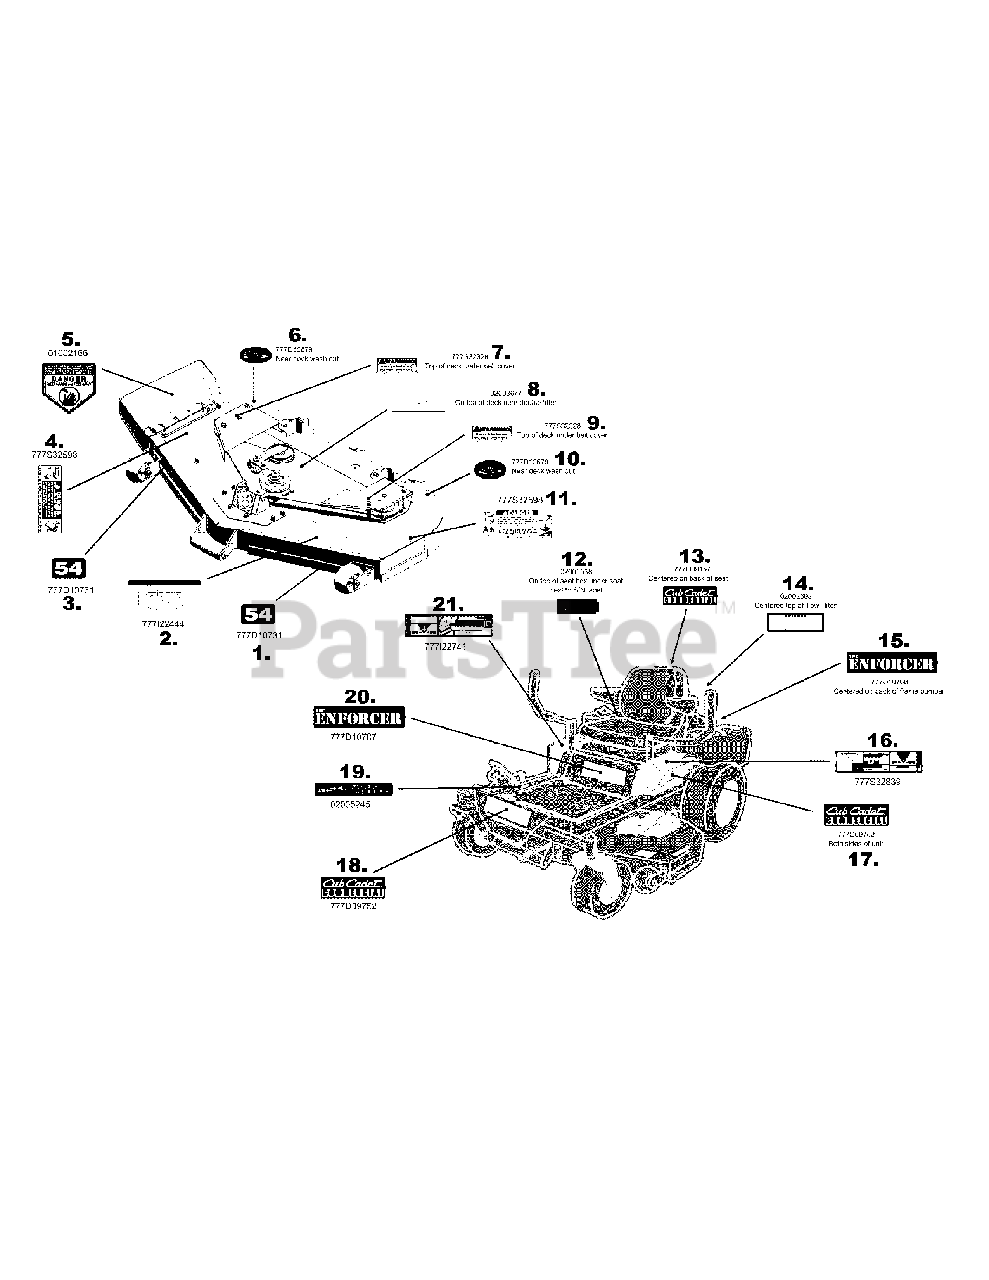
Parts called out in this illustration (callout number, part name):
1	LABEL-54" DECK
2	DECAL-50' DECK BELT RT
3	LABEL-54" DECK
4	LABEL-RZT DECK WARNG STRAIGHT
5	LABEL-HANDS & FEET WALKBEHINDS
6	LABEL-DECK WASH
7	DECAL-WARNING
8	LABEL-DECK BELT ROUTE
9	DECAL-WARNING
10	LABEL-DECK WASH
11	LABEL-RZT DECK WARNG STRAIGHT
12	LABEL-PATENT
14	LABEL-WARNING TOW HITCH
15	LABEL-ENFORCER REAR BUMPER
16	LABEL-CONTROL
17	LABEL-CUB CADET COMM
18	LABEL-CUB CADET COMM
19	LABEL-DECK HEIGHT ADJ
20	LABEL-Z FORCE
21	LABEL-Z FORCE PANEL IGNIT
